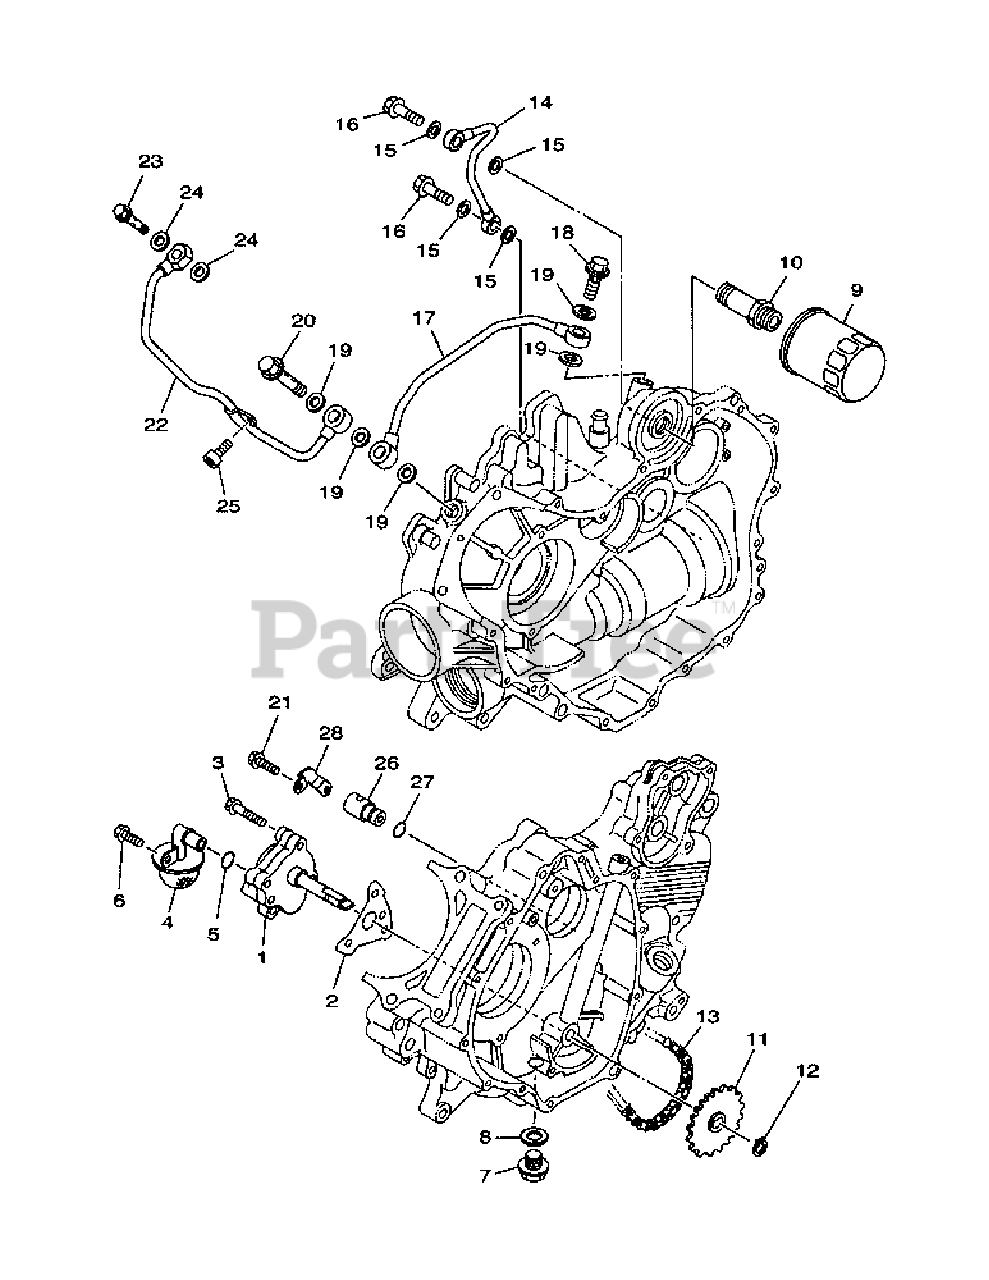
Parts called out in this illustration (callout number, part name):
1	Oil Pump-Comp
2	Paper Gasket-Oil Pump
3	Flangebolt M6X40
4	Oil Filter Net-Comp
5	O-Ring 14X2.3
6	Flangebolt M6X14
7	Screwm 14X1.5X16
8	Aluminum Washer
9	Oil Filter-Comp
10	Filter-Connecting Head
11	Sprocket-Drive
13	Chain-Oil Pump 04CH-70 Oil Pump
14	Pipe-Delivery I
15	Washer 8×15×2
17	Pipe-Delivery II
18	Bolt M14X1.5X28
19	Washer
20	Bolt M14X1.5X50
21	Flangebolt M6X14
22	Pipe-Delivery III
23	Bolt M10X1.25X30
24	Washer10.2×16×1.2
25	Flangebolt M6X12
26	Relief Valve-Comp
27	O-Ring 10X2.45
28	Plate-Relief Valve
